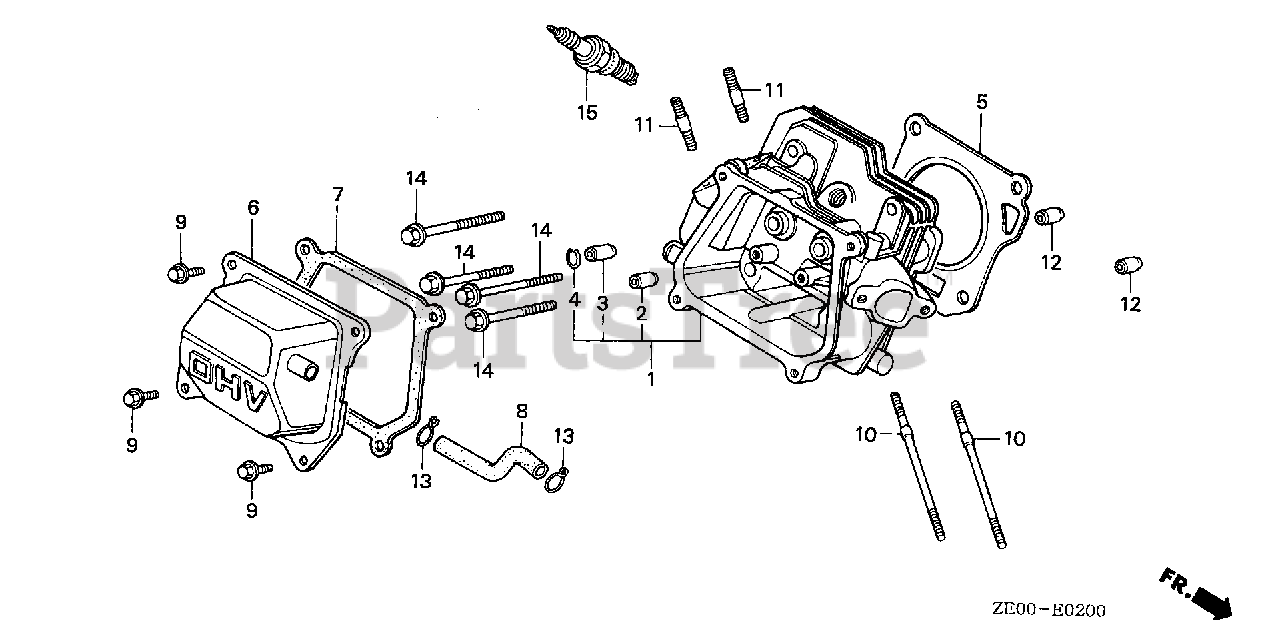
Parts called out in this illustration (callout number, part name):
1	CYLINDER HEAD
1	CYLINDER HEAD (NOT AVAILABLE)
2	GUIDE, VALVE (OVER SIZE)
3	GUIDE, EX. VALVE (OVER SIZE)
4	CLIP, VALVE GUIDE
5	GASKET, CYLINDER HEAD
6	COVER, HEAD
7	GASKET, HEAD COVER
8	TUBE, BREATHER
9	BOLT, FLANGE (6X12) (CT200)
9	BOLT, FLANGE (6X13) (CT200)
10	BOLT, STUD (6X112) (NOT AVAILABLE)
10	BOLT, STUD (6X109)
10	BOLT, STUD (6X112)
11	BOLT, STUD (8X32)
12	PIN, DOWEL (10X16)
14	BOLT, FLANGE (8X55)
15	SPARK PLUG (BPR6ES) (NGK)
15	SPARK PLUG (W20EPR-U) (DENSO)
